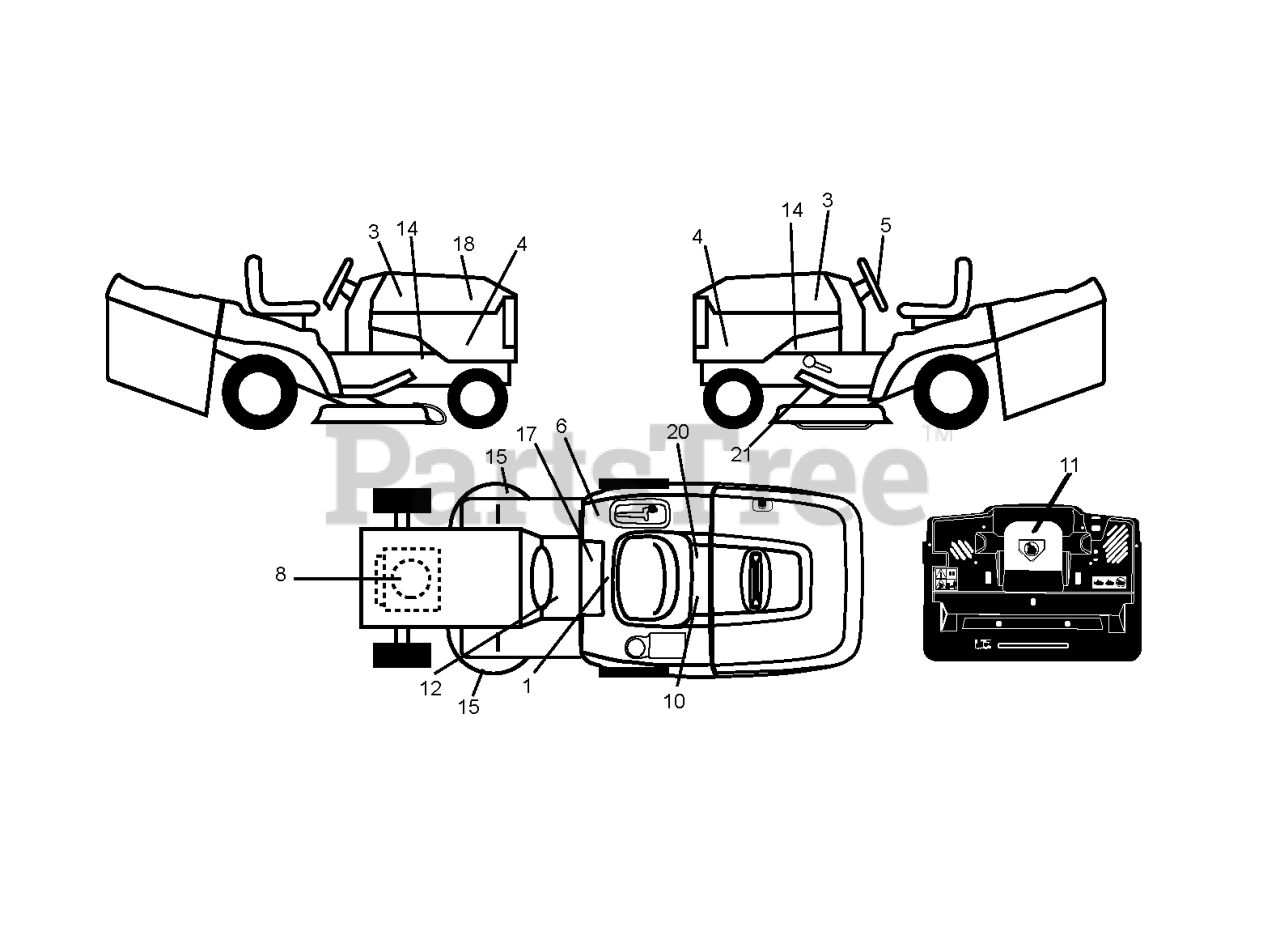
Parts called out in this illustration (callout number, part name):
1	LABEL
3	DECAL.HOOD.NAMELOGO.HUSQ
5	DECAL.WHEEL.STRG.LGN.H
6	Decal, Fender 100 DB/CE
8	DECAL
10	DECAL BTRY SYMBOLS
11	DECAL.INTERNATIONL.CUTFINGER
12	DECAL
17	DECAL PARK BRAKE
20	DECAL.BYPASS.FENDER.CRD.LT.YT
